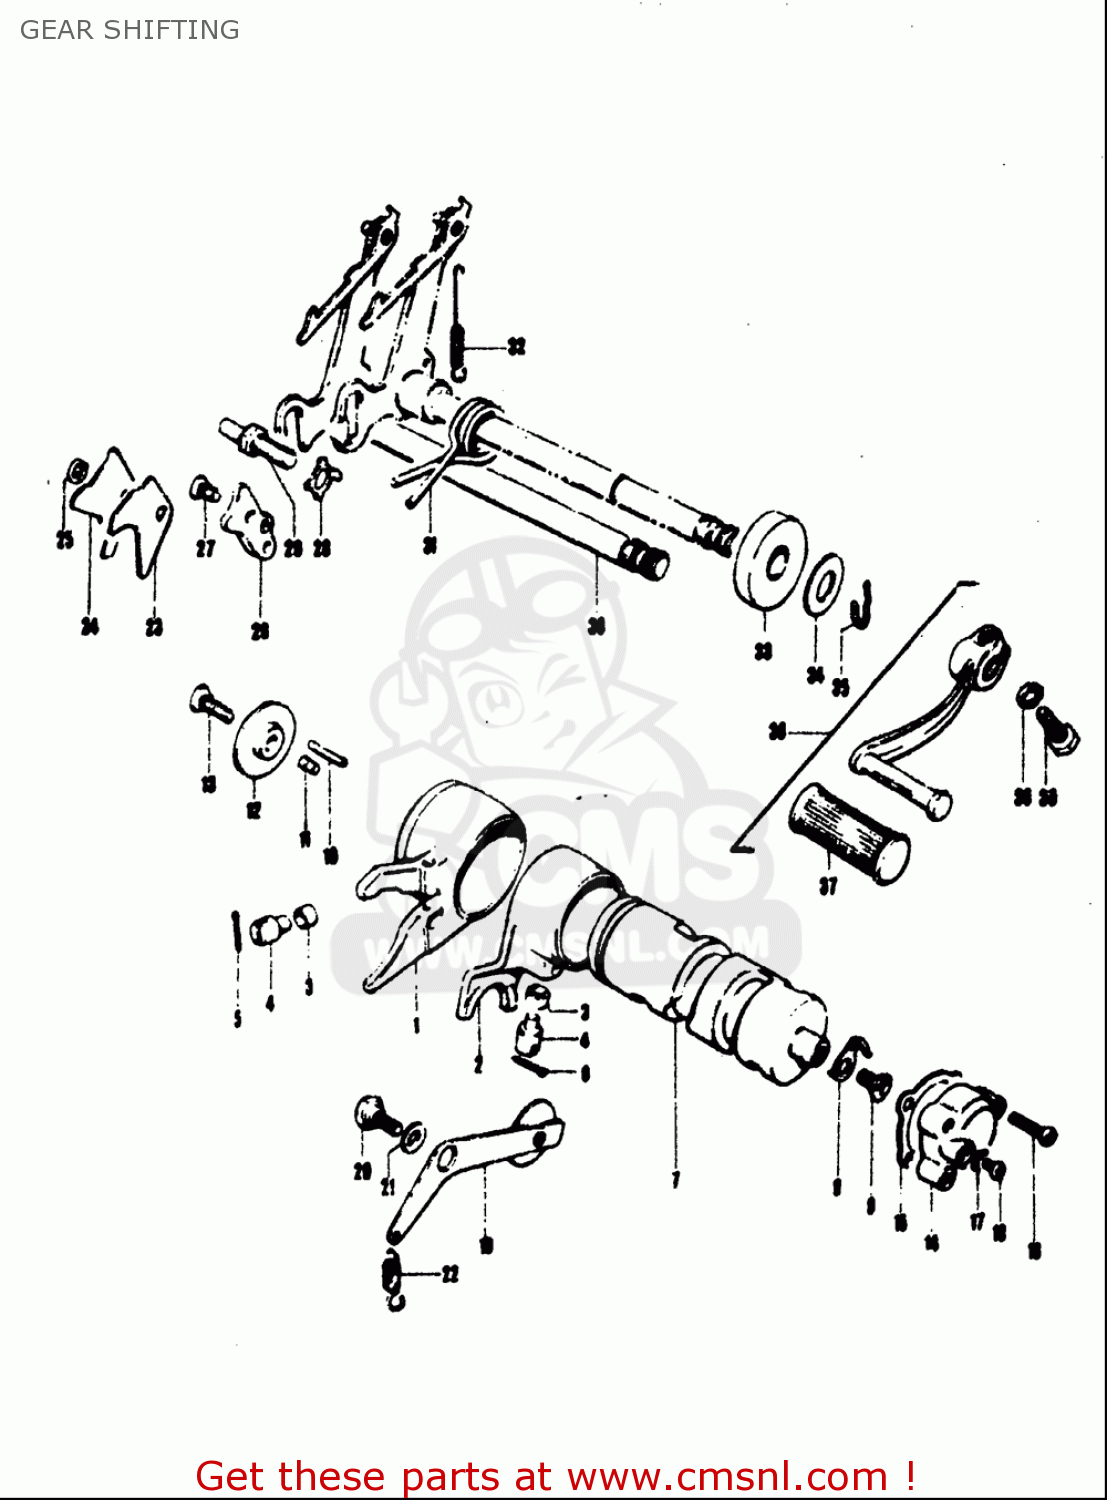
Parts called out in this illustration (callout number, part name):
3	SPACER(6X9.8X6)
4	PIN
5	PIN, COTTER
6	PIN
8	CONTACT,GEAR SHIFT SWITCH
10	PIN(4X20)
11	PIN
12	RETAINER,GEAR SHIFT CAM DR PIN
14	BODY,CHANGE SWITCH
15	GASKET,GEAR SHIFT SWITCH (NAS)
16	SCREW 4X16
17	WASHER
18	SCREW
20	WASHER (6.5X13X1)
21	BOLT(6X16.1)
25	E RING
26	GEAR SHIFTING CAM STOPPER PAWL
27	SCREW
32	SPRING
33	SEAL,OIL (12X22X9)
34	WASHER (12.5X26X1.6)
35	CIRCLIP,12 MM
37	RUBBER,GEAR SHIFT PEDAL
38	WASHER,LOCK
39	BOLT
